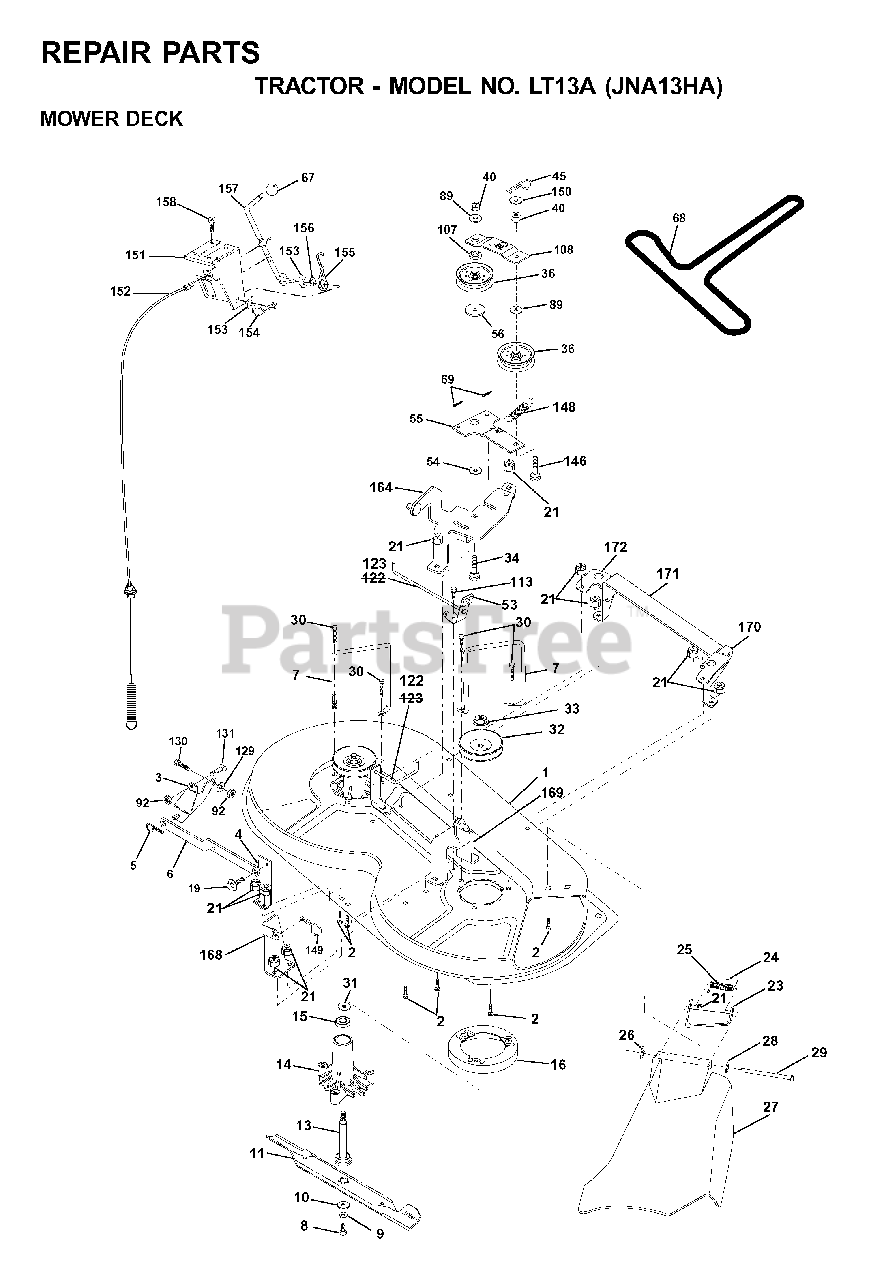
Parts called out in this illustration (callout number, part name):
2	BOLT
3	BRKT ASM SWAY BAR
5	RETAINER-SPRNG RB
6	REAR SUSP ARM
7	KEEPER LH
8	BLADE BOLT
9	LOCKWASHER
10	WASHER.BLADE
11	BLADE, HI-LIFT 36" PREMIUM
13	SHAFT ASM VENT
14	HSG MANDREL
16	STRIPPER, MWR ROUND
19	BOLT SHD 5/16-18
21	LOCKNUT
23	BRACKET ASM DEFLECTOR
24	CAP-SLEEVE LT
25	SPRING TORSION
26	NUT PUSH M
28	WASHER
29	HINGE ROD
30	SCREW THDROL ROLLING WASHER HD
31	WASHER
32	PULLEY, MANDREL
33	NUT
34	BOLT
36	FLAT IDLER PULLEY
40	LOCKNUT
45	RETAINER M
53	BRAKE ASSEMBLY
54	HARDENED WASHER
55	IDLER ARM
56	SPACER.RETAINER.MOWER
67	KNOB T (3/8 HOLE)
69	COTTER PIN
89	WASHER GT
92	NUT
107	SPACER.IDLER.ARM
108	STIFFENER.IDLER.ARM
129	WASHER
131	BOLT D
146	BOLT, CARRIAGE IDLER
148	IDLER RETURN SPRING
149	SPRING.RETAINER.YELLOW.ZINC
150	WASHER PM
151	BRACKET, CLUTCH CABLE
153	WASHER FLAT 3/8"
154	SPRING RETAINER
155	SPRING RETENTION LEVER
156	SPACER CLUTCH CABLE
157	ROD CLUTCH CABLE 3/8"
158	SCREW LT
171	BRACE
